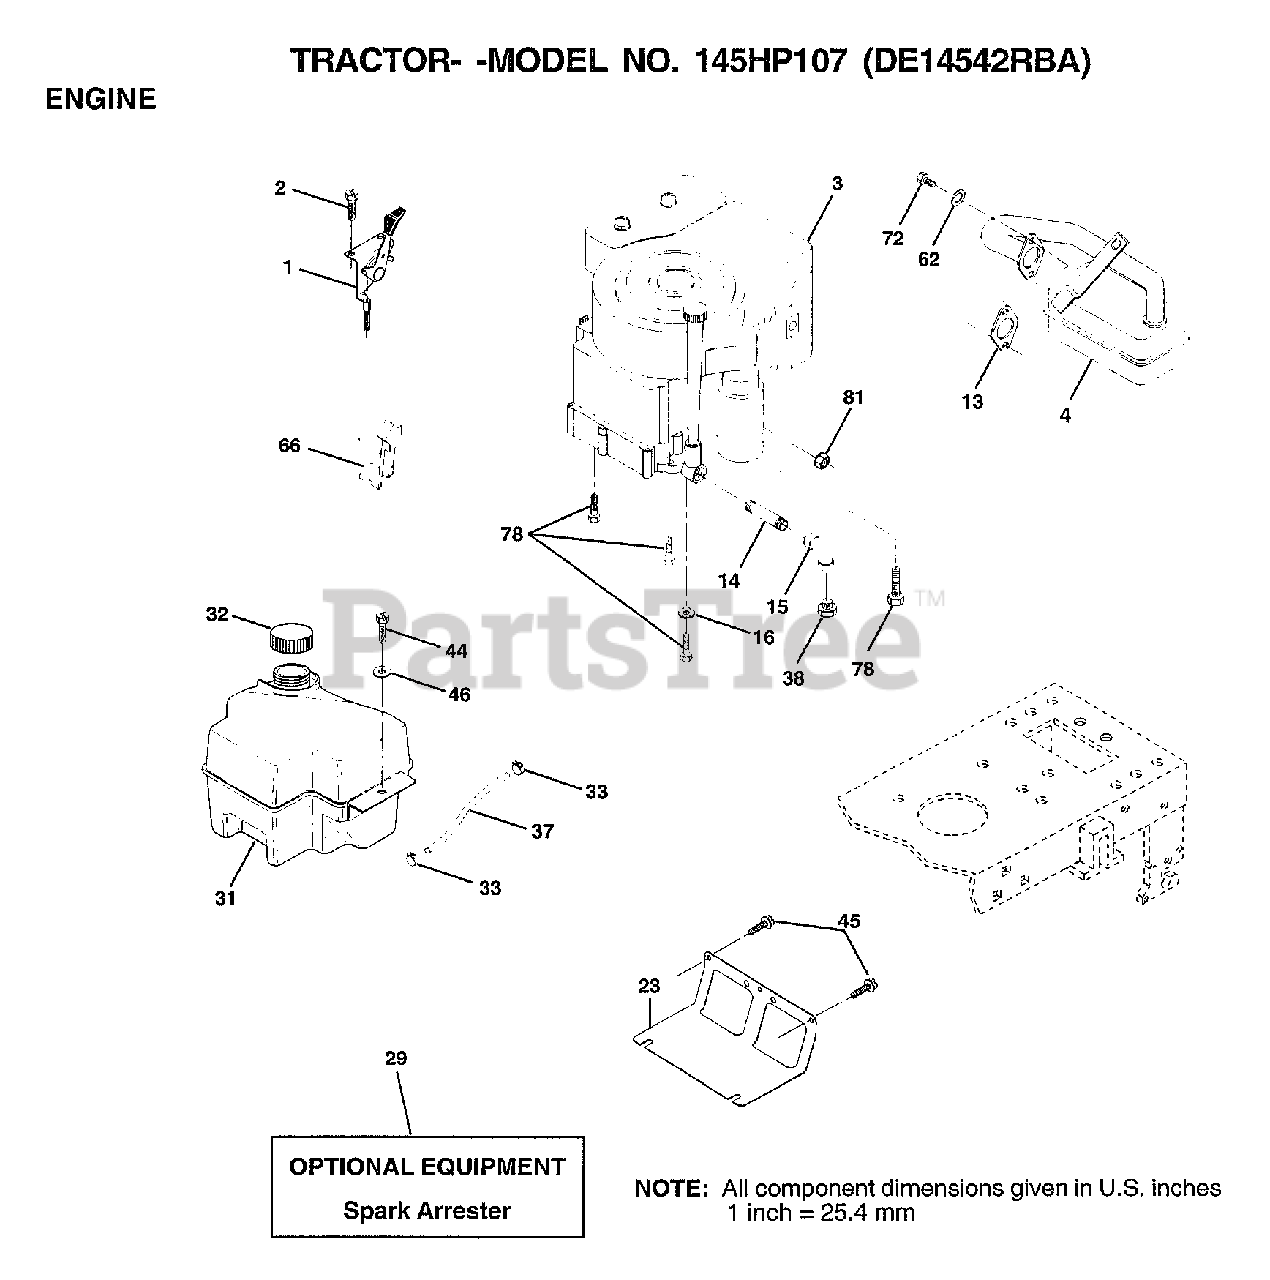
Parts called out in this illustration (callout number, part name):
1	CONTROL.THTL.23.5
2	SCREW LT
4	MUFFLER
14	PIPE NIPPLE
15	ELBOW
16	LOCKWASHER
23	SHIELD BROWNING
31	TANK.FUEL.FRONT.
32	CAP ASM FUEL
33	HOSE CLAMP
37	LINE FUEL
44	SCREW
45	SCREW
46	WASHER
62	LOCKWASHER
66	"STOP,DASH THROTT"
72	SCREW
78	SCREW
81	NUT
